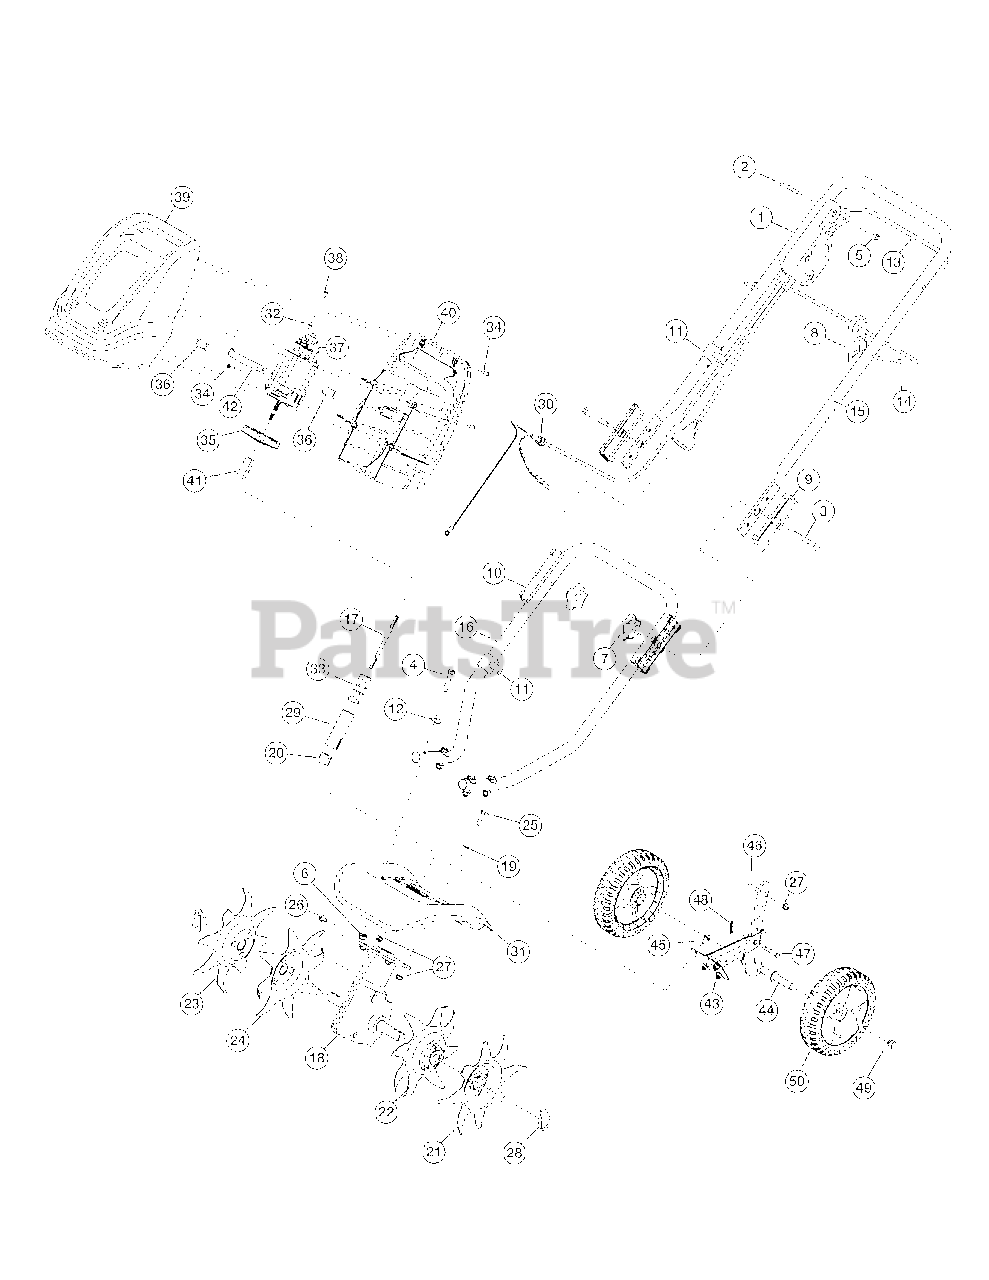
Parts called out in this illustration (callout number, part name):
1	Switch Assembly
4	Screw
7	Knob
8	Cord Retainer
9	Upper Handle Insulator
10	Lower Handle Insulator
11	Cable Guide
12	Saddle Washer
13	Control Bail
15	Upper Handle
16	Lower Handle
17	Flex Shaft
18	Gearbox
19	Washer
20	Sleeve
21	Outer Tine Assembly
22	Inner Tine Assembly
23	Outer Tine Assembly
24	Inner Tine Assembly
25	Screw
28	Lynch Pin
29	Boom Tube
30	Cord Bushing
31	Tine Shield
32	Lock Washer
33	Flex Tube Assembly
36	Motor Pad
37	Motor Assembly
39	Front Motor Cover
40	Rear Motor Cover
41	Motor Hub
42	Motor Strap
43	Bracket Assembly
44	Wheel Support Bracket Assembly
46	Belt Guard Pin
47	Clevis Pin
48	Cotter Pin
49	Push Cup
50	Wheel (Incl Ref No. 49)
